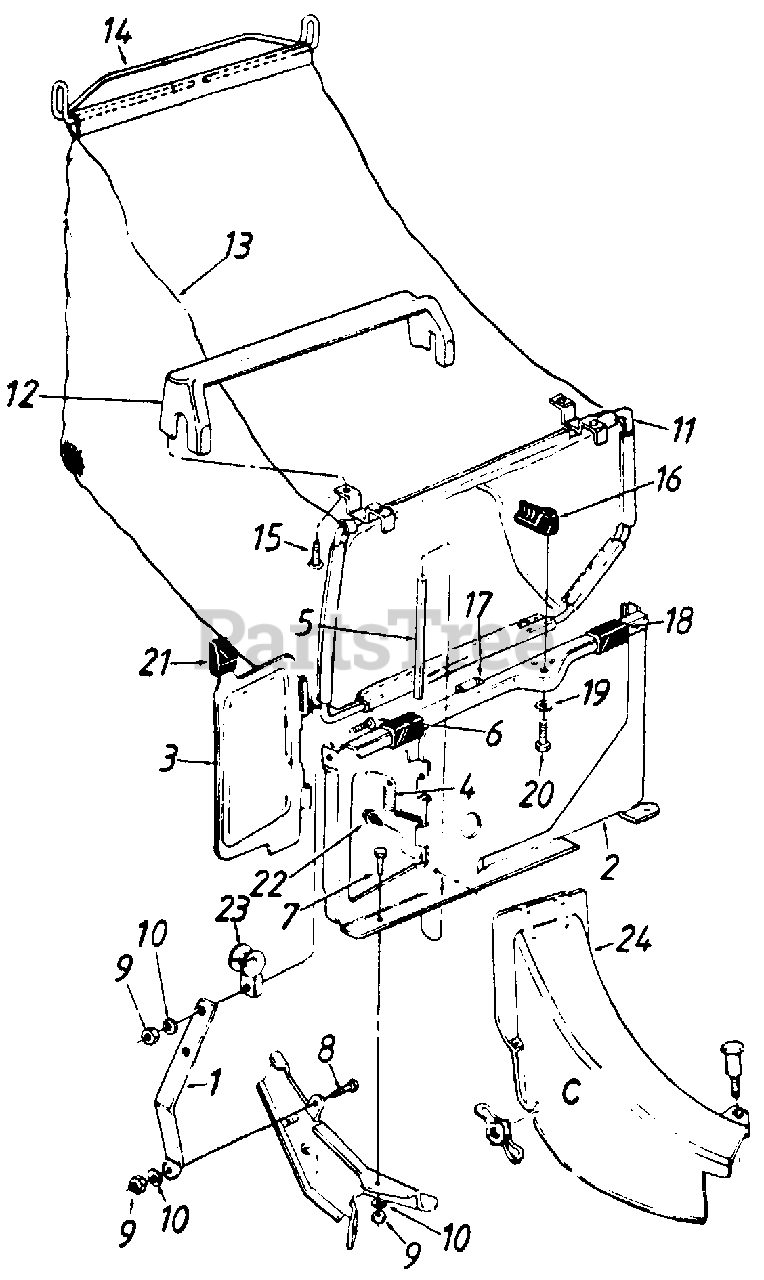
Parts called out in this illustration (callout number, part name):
1	Panel Support Brkt.
2	Top Catcher Panel Ass'y.
3	Top Discharge Door
4	Torsion Spring
5	Pivot Pin
6	Truss Mach. Scr. 1/4-20 x .75" Lg.
7	Hex Bolt 1/4-20 x .50" Lg.'
8	Hex Bolt 1/4-20 x .62" Lg.
9	Hex Nut 1/4-20 Thd.
10	L-Wash. 1/4" I.D.
11	Front Grass Catcher Frame
12	Grass Catcher Handle
13	Grass 8ag
14	Upper Bag Handle
15	Hex AB-Tap Scr. #12 x 1.0"
16	Grass Catcher Locking Knob
17	Foam Strip 1" Lg.
18	Panel Clip
19	Spring Wash. .32" I.D.
20	Hex 801t 1/4-20 x .62" Lg.
21	Door Grip
22	Hex B-Tap Scr. #10 x .38"
23	Rope Guide
24	Top Discharge Chute Ass'y.
